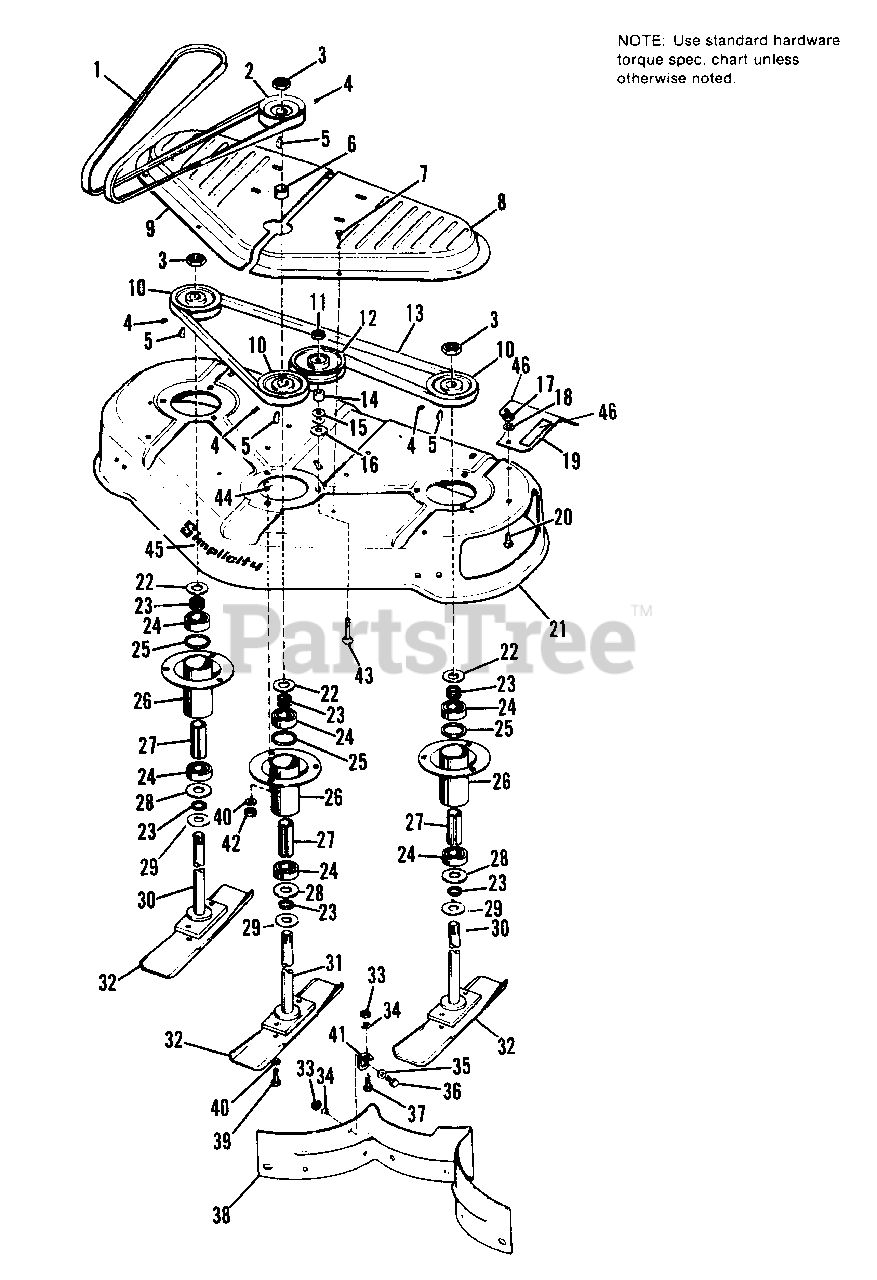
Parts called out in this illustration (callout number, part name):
1	BELT, V, Drive
2	PULLEY, Drive
3	LOCKNUT, Jam, 3/4-16
4	SETSCREW, 5/16-18 x 3/8
5	KEY, Woodruff, #6
7	SCREW, Hex, Self Tapping, 1/4-20 x 7/8
8	COVER, L.H.
9	COVER, R.H.
11	LOCKNUT, Hex, 3/8-16
12	PULLEY, Idler
15	WASHER, Plain, 5/16
16	WASHER, Plain, 1/2
17	NUT, Hex, Full, 5/16-18
18	LOCKWASHER, 5/16
19	DEFLECTOR
20	BOLT, Carriage, 5/16-18 x 3/4
21	HOUSING, Mower
24	BEARING, Ball
25	RING, Backing
26	TUBE ASSY., Arbor
30	ARBOR ASSY.
31	DRIVE ASSY., Arbor
33	NUT, Hex, Full, 1/4-20
34	LOCKWASHER, 1/4
35	WASHER, Plain, 1/4
36	CAPSCREW, Hex Hd., 1/4-20 x 5/8
37	SCREW, Hex, Self Tapping, 1/4-20 x 7/8
39	CAPSCREW, Hex Hd., 3/8-16 x 5/8
40	LOCKWASHER, 3/8
42	NUT, Hex, Full, 3/8-16
43	BOLT, Carriage, 3/8-16 x 1-3/4
44	BOLT, Carriage, 3/8-16 x 3/4
45	DECAL, Simplicity
46	DECAL, Safety
